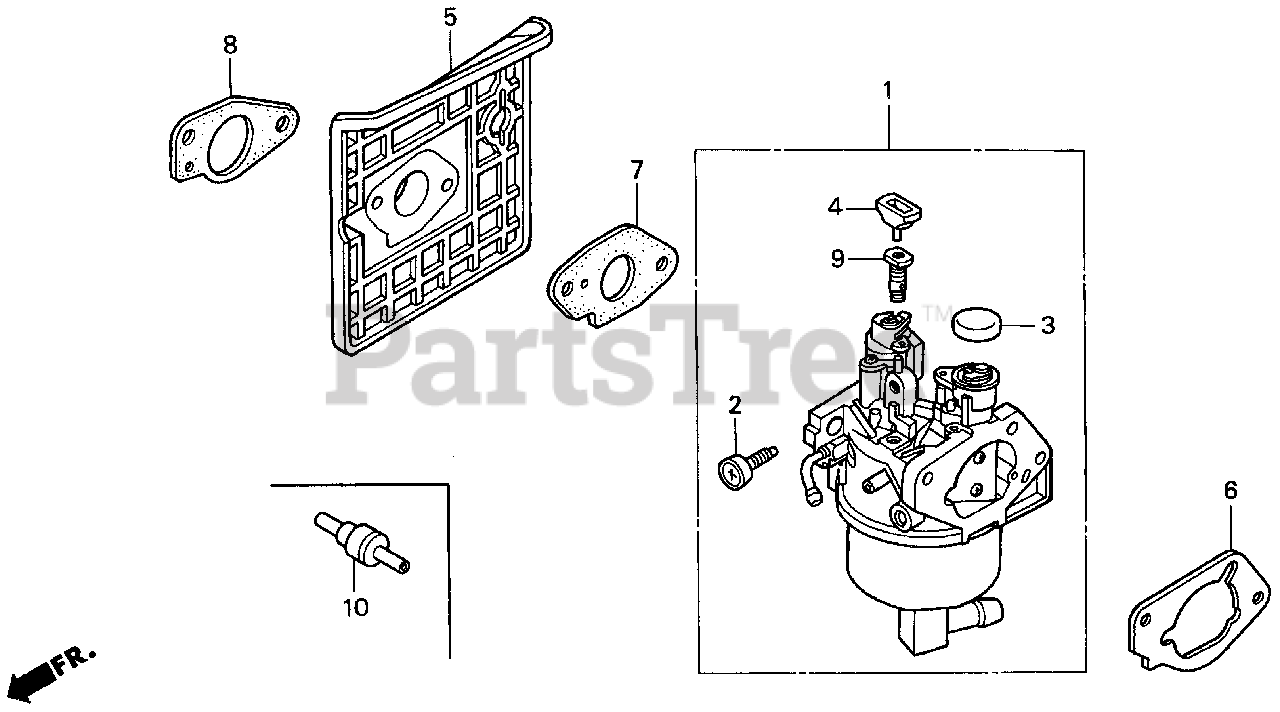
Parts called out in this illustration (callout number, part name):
1	CARBURETOR ASSY. (BEL6A C)
2	SCREW, THROTTLE STOP
3	CAP, CHOKE LEVER DUST
4	COLLAR, SET
5	INSULATOR, CARBURETOR
6	SPACER, CARBURETOR
7	GASKET, CARBURETOR
8	GASKET, INSULATOR
9	VALVE, DASHPOT CHECK
10	JET, PILOT (#45)
